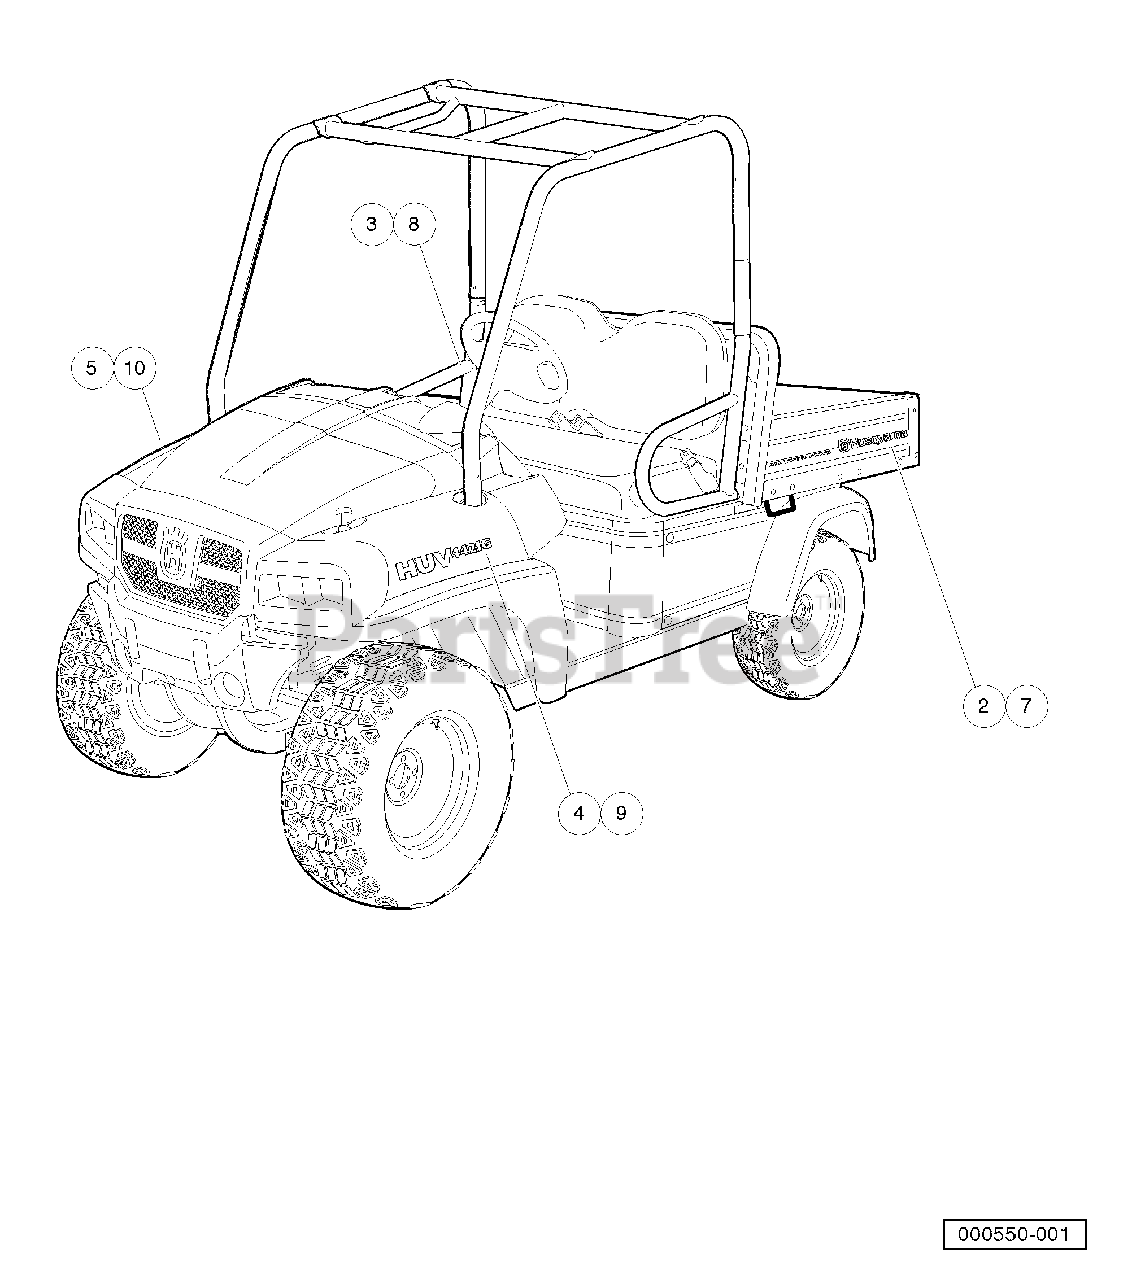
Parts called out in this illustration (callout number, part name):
2	Decal, Bed, Huv, Orange, Ds
3	Decal, Bed, Huv, Orange, Ps
4	Decal, Huv 4421g, Orange, Ds
5	Decal, Huv 4421g, Orange, Ps
6	Instl,decal,huv4421g,olv Grn
7	Decal, Bed, Huv, Olv Grn, Ds
8	Decal, Bed, Huv, Olv Grn, Ps
9	Decal, Huv 4421g, Olv Grn, Ds
10	Decal, Huv 4421g, Olv Grn, Ps
